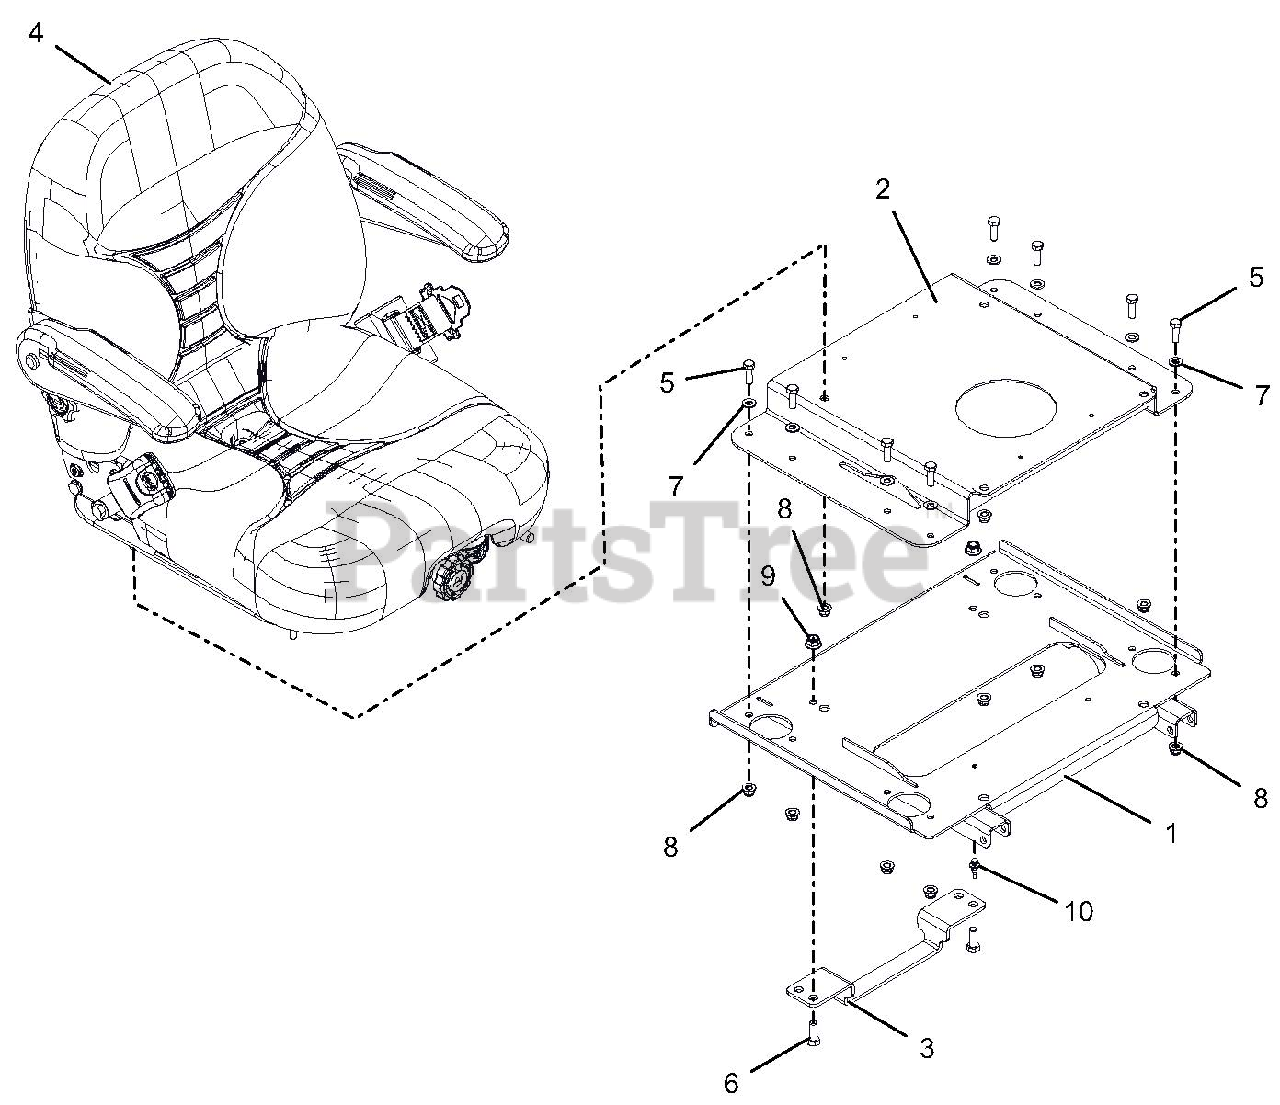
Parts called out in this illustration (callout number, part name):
1	WLDMT, SEAT ISO MOUNTING-RED
2	SEAT BASE MOUNTING WLDM - RED
3	BRACKET - SEAT LATCH
4	SEAT,SUSP,W/SEAT BELT,LT GRY
5	@BLT-HEX .31-18X1.00 GR5 YWZC
6	@BLT-HEX .38-16X1.00 GR5 YWZC
7	@WSHR-FL-STL.344X.688X.065YWZC
8	@NUT-LK-NYL-FLG .31-18 YWZC
9	@NUT-LK-NYL-FLG .38-16 YWZC
10	CABLE TIE W/ TREE (.25 HOLE)
